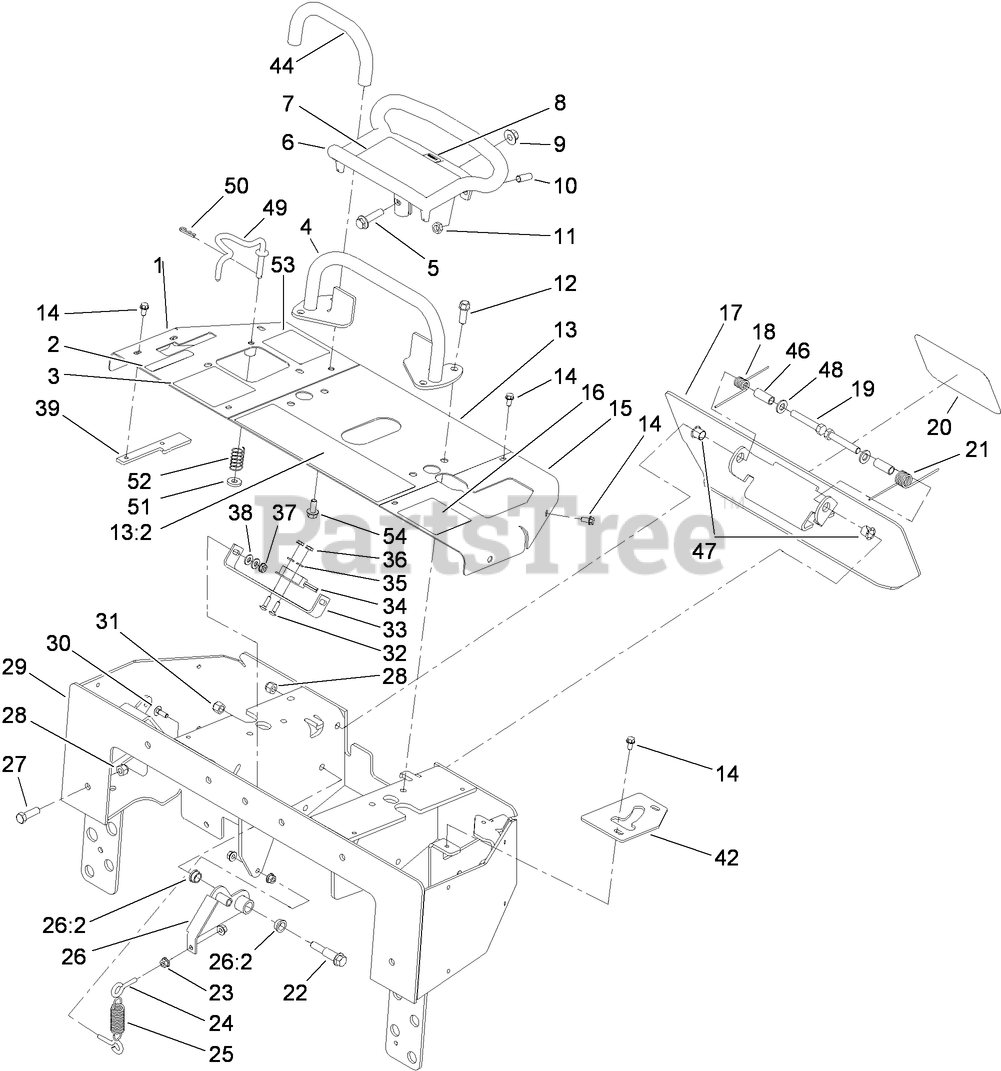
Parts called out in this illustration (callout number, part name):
1	PANEL-RH
2	DECAL-BRAKE
3	DECAL-CONTROL, LOADER
4	BAR-REFERENCE
5	SCREW-HHF
6	HANDLE-CONTROL
7	DECAL-TRACTION
8	DECAL
9	NUT-FLANGE
10	SCREW-SET
11	NUT-JAM
12	SCREW-TAPTITE
13	CENTER PANEL ASM
13:2	DECAL-DANGER
14	SCREW-HWH
15	PANEL-LH
16	DECAL-CONTROL, AUXILIARY
17	PLATE-REVERSE
18	SPRING-TORSION, LH
19	SCREW-HH
21	SPRING-TORSION, RH
22	BOLT-SHOULDER
23	NUT-HHF
24	BOLT-EYE
25	SPRING-EXTENSION
26	NEUTRAL CENTERING LEVER ASM
26:2	BUSHING-FLANGE
27	SCREW-HH
28	NUT-LOCK, NI
29	PANEL-CONTROL
30	BOLT-CARR
31	NUT-LOCK
32	SCREW-CARR
33	PLATE-SWITCH
34	SWITCH-PROXIMITY
35	WASHER-FLAT
36	NUT-KEPS
37	NUT-KEPS
38	WASHER-FLAT
39	PLATE-LOCKING, BRAKE
42	PLATE-STOP
44	BAR-REFERENCE
46	SPACER-SPRING
47	BUSHING-NYLINER
48	WASHER-FLAT
49	ROD-INTERLOCK
50	PIN-COTTER
51	WASHER-FLAT
52	SPRING-CONTROL
53	DECAL-LOADER LOCK
54	SCREW-HHF
